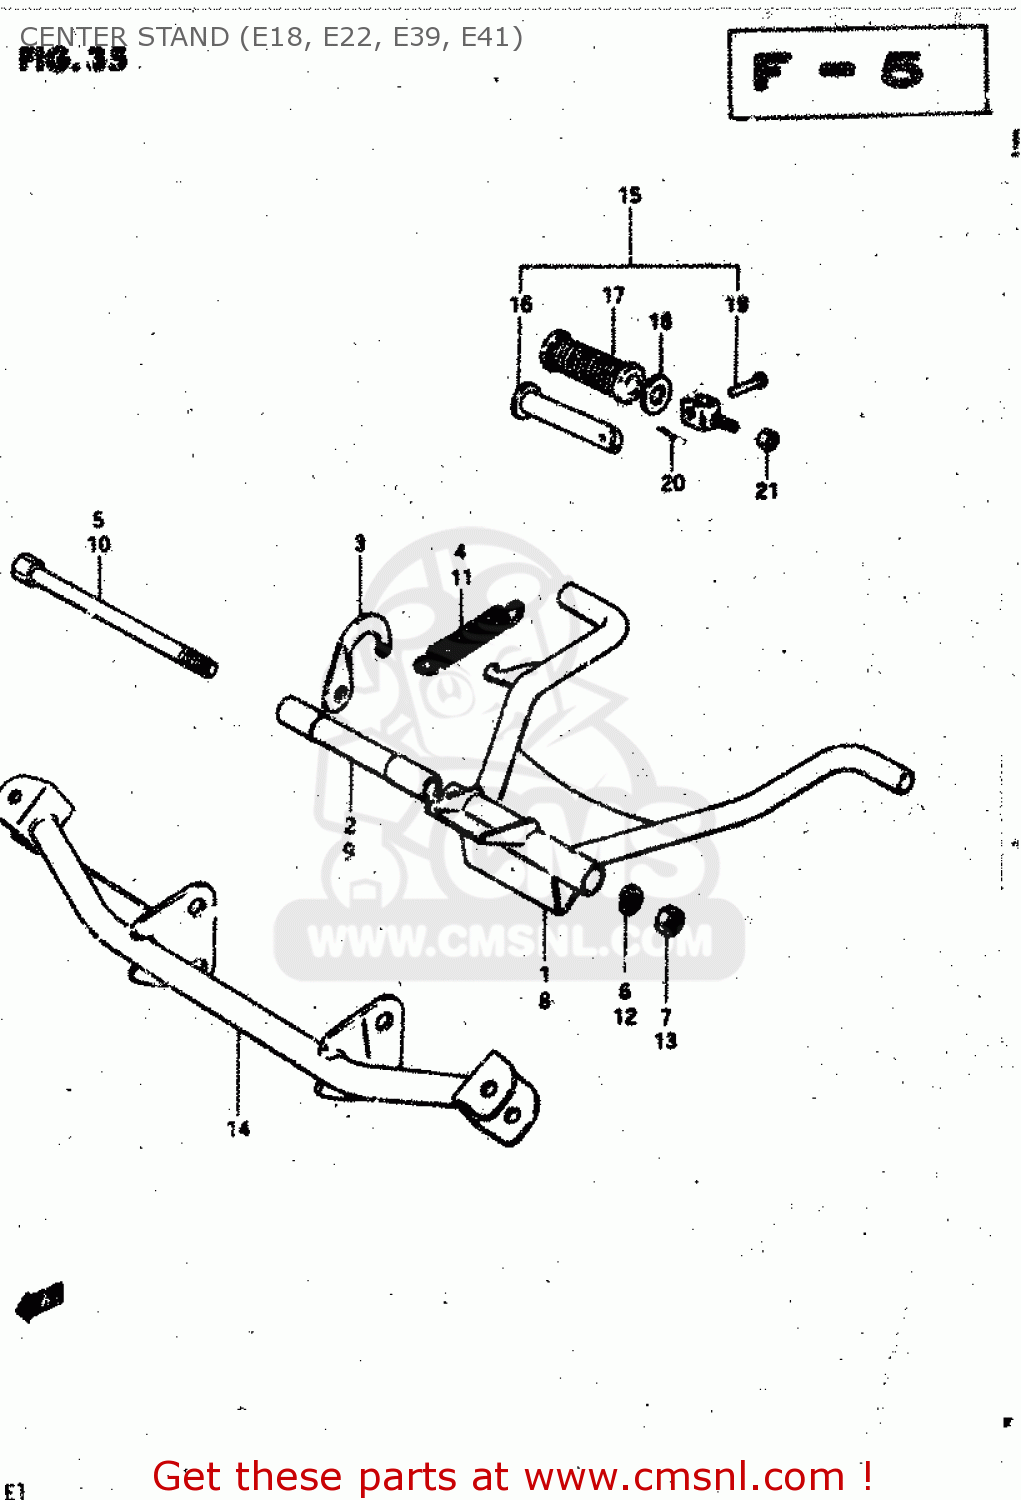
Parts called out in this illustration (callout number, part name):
1	STAND, CENTER
2	SPACER
3	HOOK,CENTER STAND SPRING
4	SPRING
5	BOLT
6	LOCK WASHER
7	NUT
8	STAND, CENTER
9	SPACER
10	BOLT
11	SPRING
12	LOCK WASHER
13	NUT
14	BAR, FRONT FOOTREST
15	FOOTREST ASSEMBLY,REAR
16	BAR,FOOTREST RUBBER
17	RUBBER,PILLION FOOTREST
18	WASHER (19.5X32X2)
19	PIN
20	PIN 20X20
21	NUT
